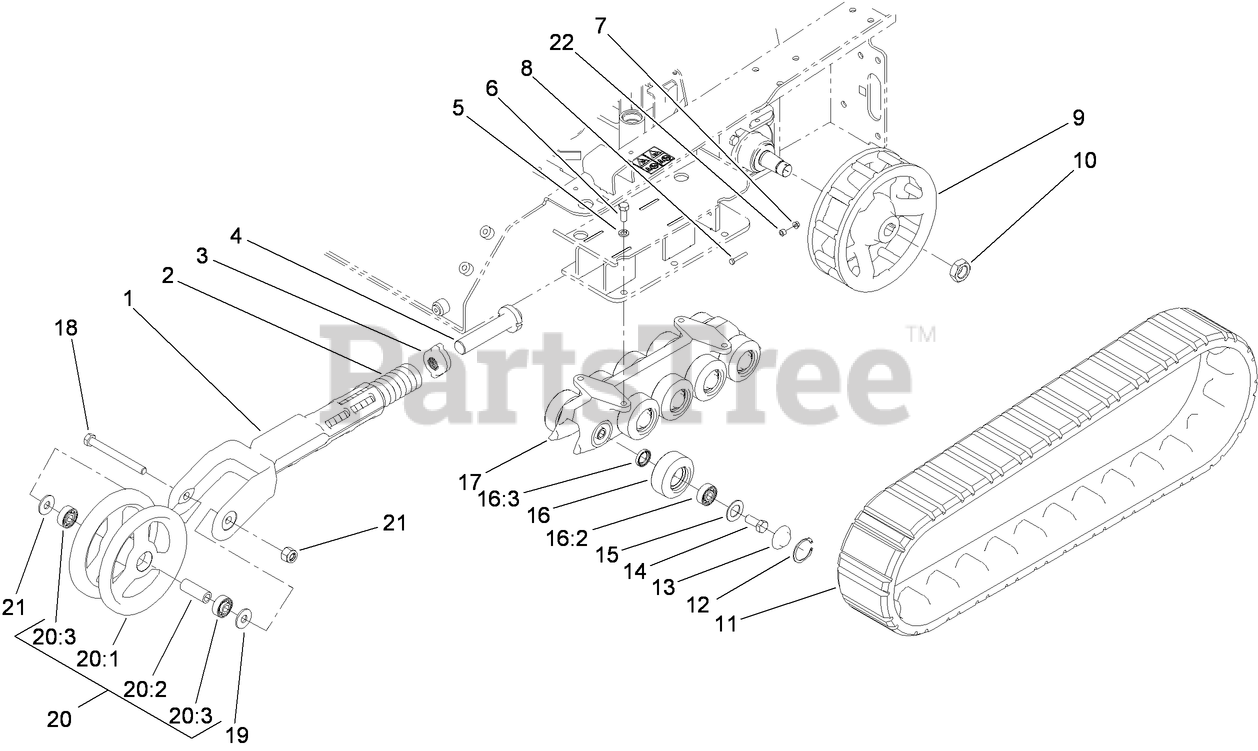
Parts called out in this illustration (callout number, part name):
1	ARM-TENSIONER
2	SPRING-COMPRESSION
3	BLOCK-TENSIONER
4	BOLT-TENSIONER
5	WASHER-LOCK
6	SCREW-HH
7	NUT-HHF
8	SCREW-HH
9	WHEEL-DRIVE
10	NUT-HEX
11	TRACK
12	RING-SNAP, INTERNAL
13	CAP-WHEEL, BEARING
14	SCREW-HH
15	Gasket-Bogie
16	Road Wheel ASM
16:2	BEARING
16:3	SEAL-OIL
17	GUIDE-TRACK
18	SCREW-HH
19	WASHER-FLAT
20	TENSIONER WHEEL ASM
20:1	WHEEL-TENSIONER
20:2	SPACER-WHEEL, TENSIONER
20:3	BEARING
21	NUT-HEX
22	SPACER
